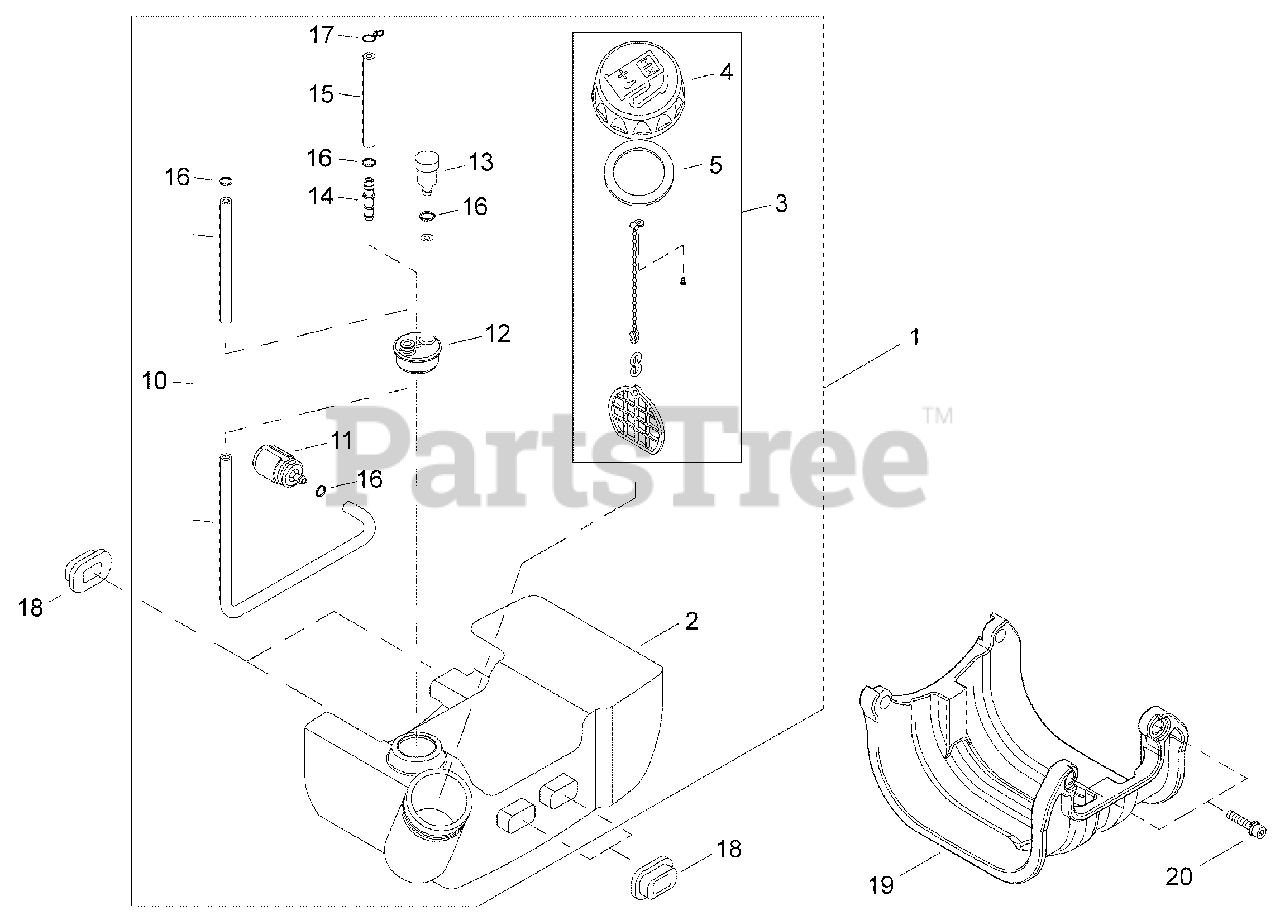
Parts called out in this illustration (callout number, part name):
1	FUEL TANK ASSY
2	TANK, FUEL
3	CAP ASSY
4	CAP, FUEL
5	GASKET, CAP
10	PIPE - FUEL
11	FILTER, FUEL
12	GROMMET
13	ELEMENT, BREATHER
14	CONNECTOR, PIPE
15	PIPE - 50 -- BLACK
16	RING, RETAINING - 6
17	CLIP - SPRING
18	CUSHION, FUEL TANK
19	GUARD, FUEL TANK
20	SCREW - 5X20
